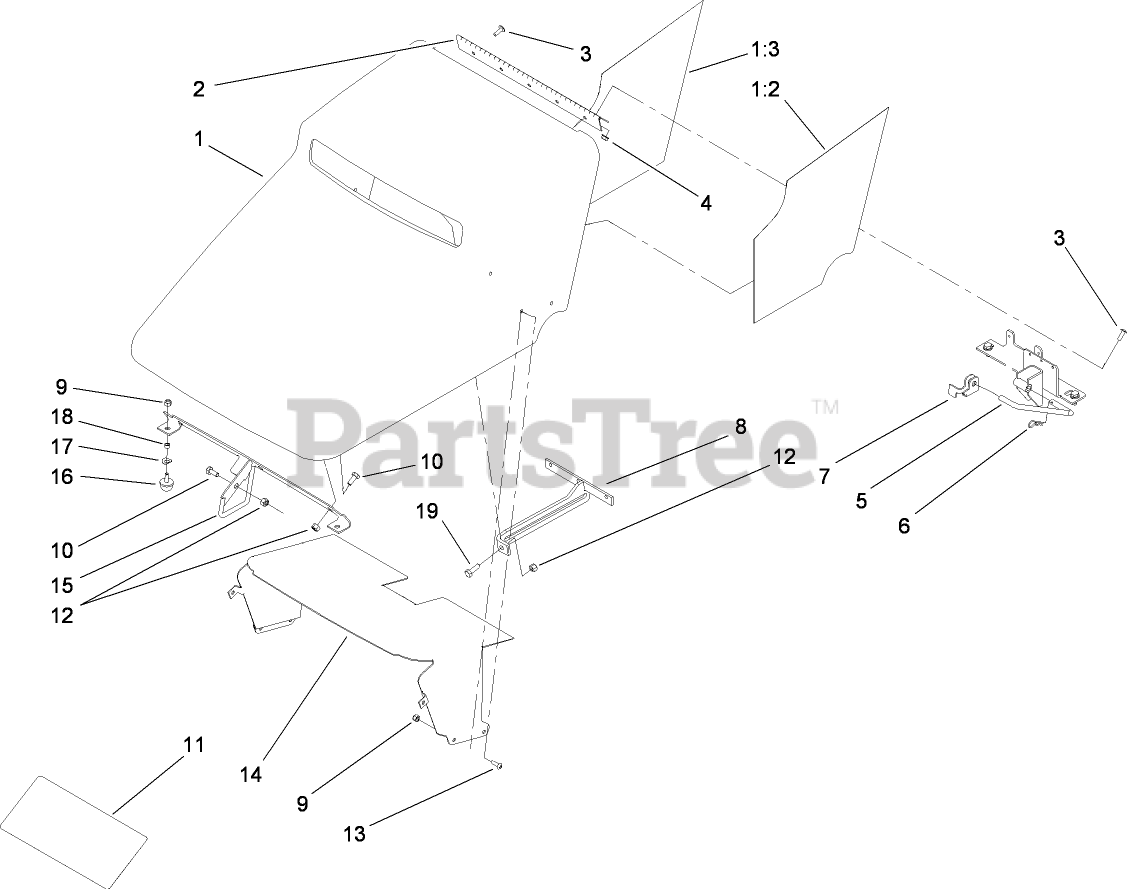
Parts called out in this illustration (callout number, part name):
1	HOOD ASM
1:2	FOILTAPE-LH
1:3	FOILTAPE-RH
2	HINGE-HOOD
3	SCREW-HEAD, TRUSS
4	NUT-HF
5	ROD-SUPPORT, HOOD
6	PIN-COTTER
7	BRACKET-LATCH, LOCKING
8	PROP ROD BRACKET ASM
9	NUT-LOCK, NI
10	SCREW-HH
11	DECAL-SERVICE, TX525
12	NUT-LOCK, NI
13	SCREW-PRH
14	BAFFLE-HOOD
15	ROD LATCH ASM
16	BUMPER
17	WASHER-SPRING
18	SPACER
19	SCREW-HH
